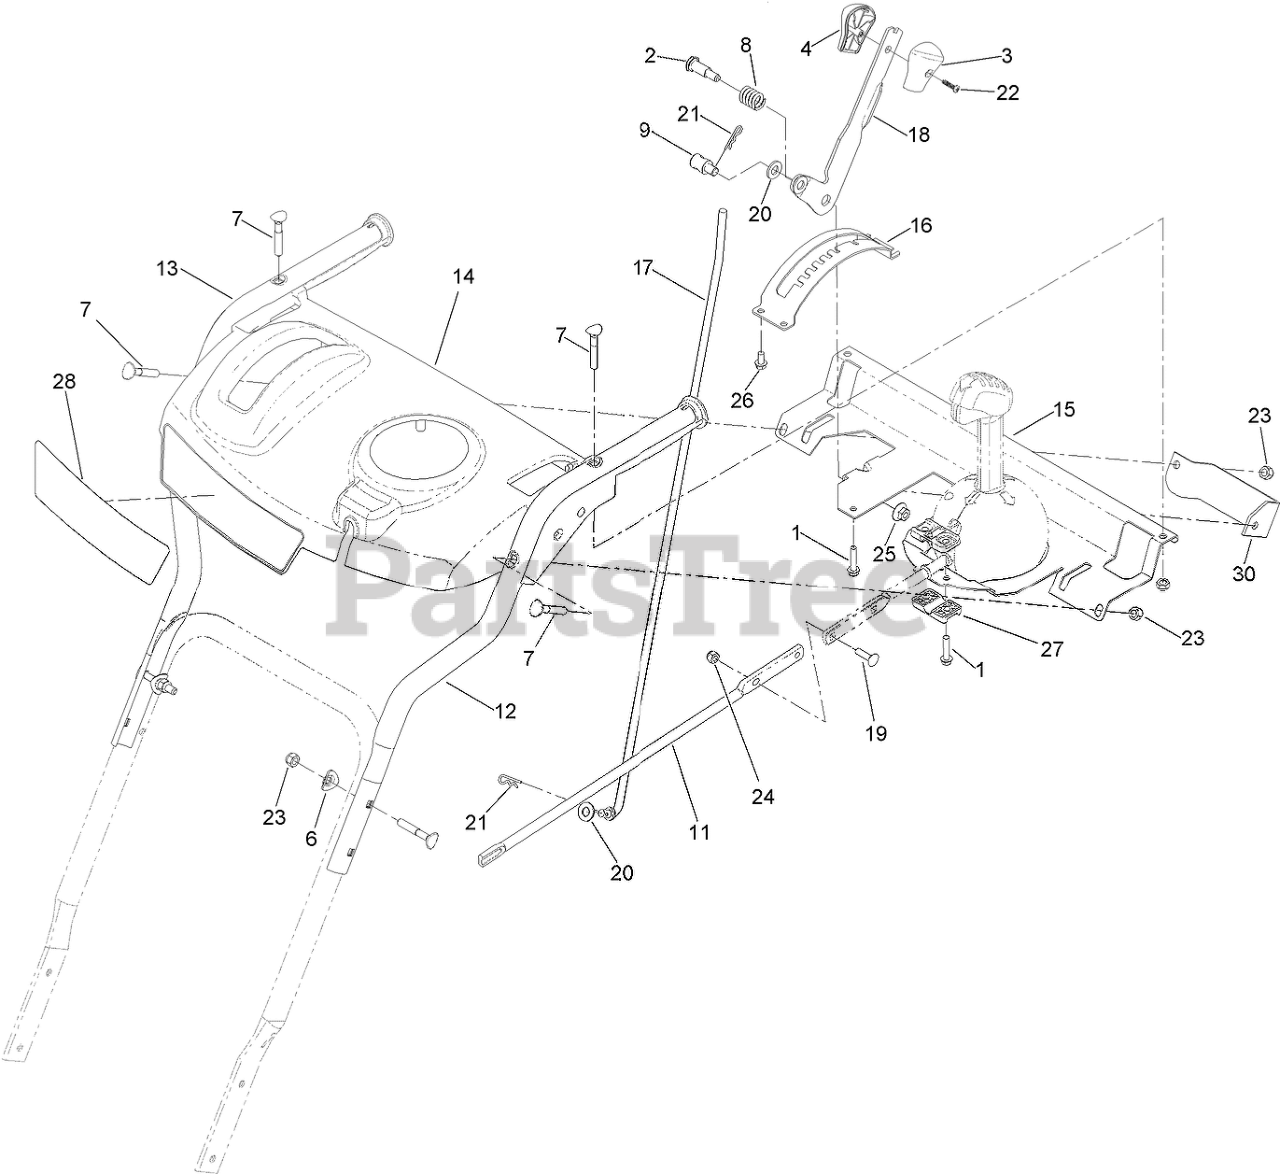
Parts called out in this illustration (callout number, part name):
1	SCREW-PLASTITE
2	SCREW-SHOULDER
3	KNOB-SHIFT, LH
4	KNOB-SHIFT, RH
6	WASHER
7	SCREW-HANDLE
8	SPRING-COMPRESSION
9	TRUNNION-ROD
11	ROD-CHUTE, FRONT
12	HANDLE-UPPER, LH
13	HANDLE-UPPER, RH
14	PANEL-CONTROL, MASTER
15	SUPPORT-PANEL, CONTROL
16	MOUNT-SELECTOR, SPEED
17	ROD-SELECTOR, GEAR
18	SELECTOR-SPEED
19	SCREW-CARR
20	WASHER-FLAT
21	PIN-COTTER
22	SCREW-PPH
23	NUT-LOCK, NI
24	NUT-LOCK, NI
25	NUT-HF
26	SCREW-PLASTITE
27	SUPPORT-ROD
28	DECAL-MODEL
30	PLATE-SUPPORT, SHIFT
